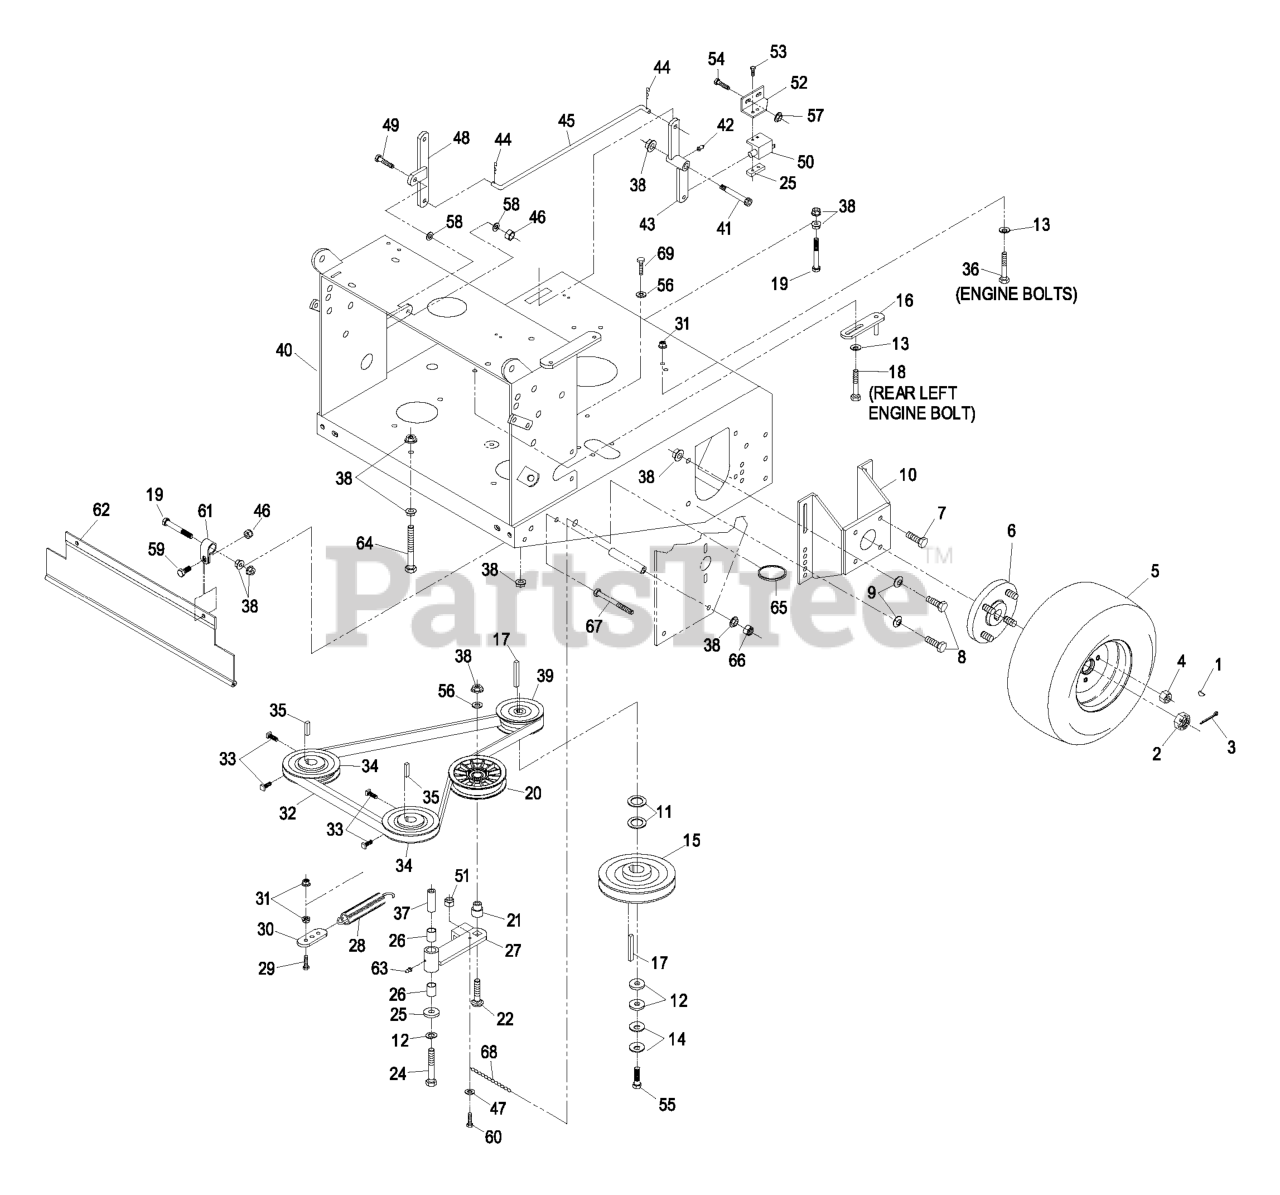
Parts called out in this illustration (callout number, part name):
1	KEY-WOODRUFF
2	NUT-HEX, SLOTTED
3	PIN-COTTER
4	NUT-LUG
5	WHEEL AND TIRE ASM
7	SCREW-HHF
8	SCREW-HH
9	WASHER-BELLEVILLE
10	MOUNT-MOTOR
11	WASHER-SPACER
13	WASHER-SPRING
14	WASHER-SPRING
16	GUIDE-BELT
18	SCREW-HH
19	SCREW-HH
20	PULLEY-IDLER, FLAT
21	BUSHING-IDLER
22	SCREW-CARR
23	WASHER-LOCK
24	BOLT-CARR
25	PLATE-TAPPED
26	SLEEVE-BEARING
27	IDLER ARM ASM
28	SPRING-EXTENSION
29	SCREW-HH
30	ANCHOR-SPRING
32	BELT-COG
33	SCREW-SET
34	SHEAVE ASM
36	SCREW-HH
37	BUSHING
38	NUT-HHF, WHIZ
39	PULLEY
40	DECK,ENGINE W/DECALS
42	FITTING-GREASE, 90 DEG
43	BELLCRANK ASM
44	PIN-COTTER
45	LINKAGE-ENGAGE, BLADE
46	NUT-LOCK, NI
47	WASHER-FLAT
49	SCREW-HH
50	SWITCH-OPEN, NORMALLY
51	NUT-LOCK, NI
52	BRACKET-SWITCH, BLADE
53	SCREW-PPH
54	SCREW-HH
55	SCREW-HH
56	WASHER-FLAT
58	WASHER-PLAIN
59	SCREW-HH
60	SCREW-HSH
61	CLIP-LOOM
62	SHIELD-DRAG
63	FITTING-GREASE
64	SCREW-HH
65	RING-SPLIT
66	NUT-LOCK, NI
67	SCREW-HH
68	CHAIN-LINK, TWIST
69	SCREW-HH
